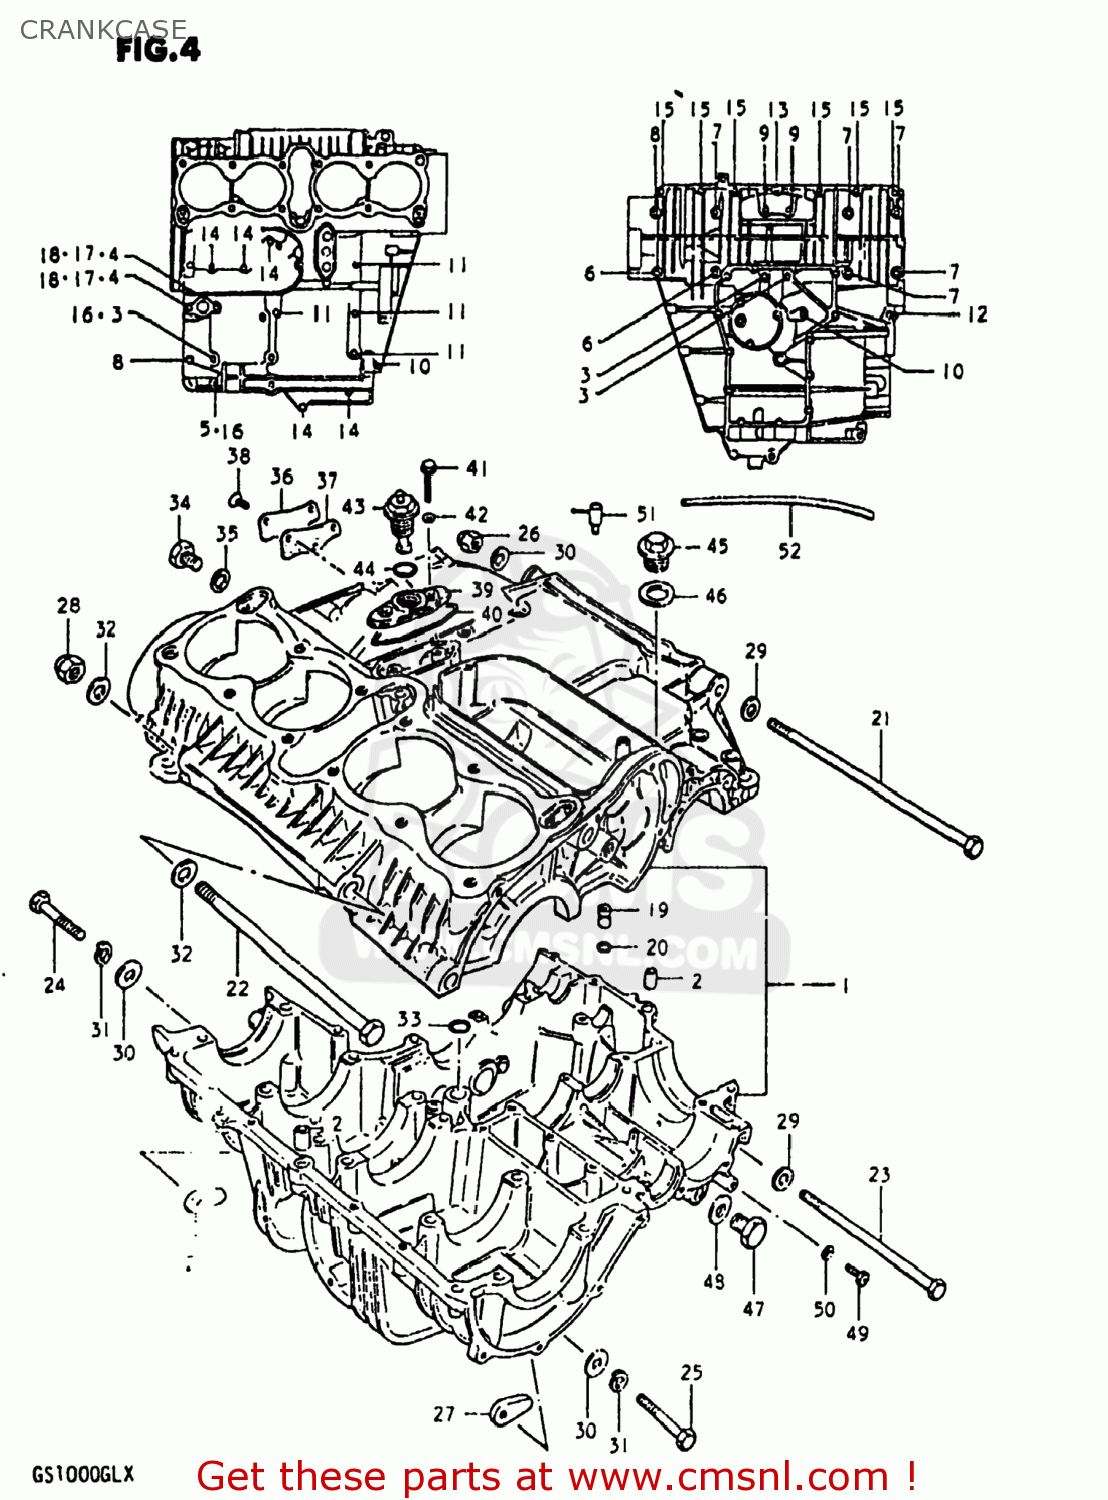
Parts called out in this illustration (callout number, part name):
1	CRANKCASE SET
2	PIN
3	BOLT
4	BOLT
5	BOLT
6	BOLT
7	BOLT 8X90
8	BOLT 8X65
9	BOLT
10	BOLT (6X90)
11	BOLT (6X75)
12	BOLT
13	BOLT ,6X50
14	BOLT,UNDER
15	BOLT 6X35
16	NUT
17	NUT
18	GASKET 8.2X14X1 (NAS)
19	UNION
20	O-RING
21	BOLT 10X270
22	SHAFT,REAR SWING ARM
23	BOLT(10X165)
24	BOLT 10X60
25	BOLT (10X50)
26	NUT
27	NUT
28	NUT 12MM
29	WASHER(10.5X20X3.2)
30	WASHER
31	LOCK WASHER
32	WASHER
33	O RING(D:3.2,ID:12.9)
34	PLUG (14X12)
35	GASKET(14X19.2X2) (NAS)
36	CAP,OIL GALLERY
37	GASKET,OIL GALLERY (MCA)
38	SCREW
39	HOUSING,OIL PRESSURE SWITCH
40	O RING,PRESSURE SWITCH HOUSING
41	BOLT
42	GASKET (NAS)
43	SWITCH ASSEMBLY
44	O RING(D:1.9,ID:18.8)
45	PLUG
46	GASKET
47	PLUG
48	GASKET(14X19.2X2) (NAS)
49	SCREW(6X10)
50	GASKET (NAS)
51	BPLUG,BEVEL GEAR BREATHER
52	HOSE
